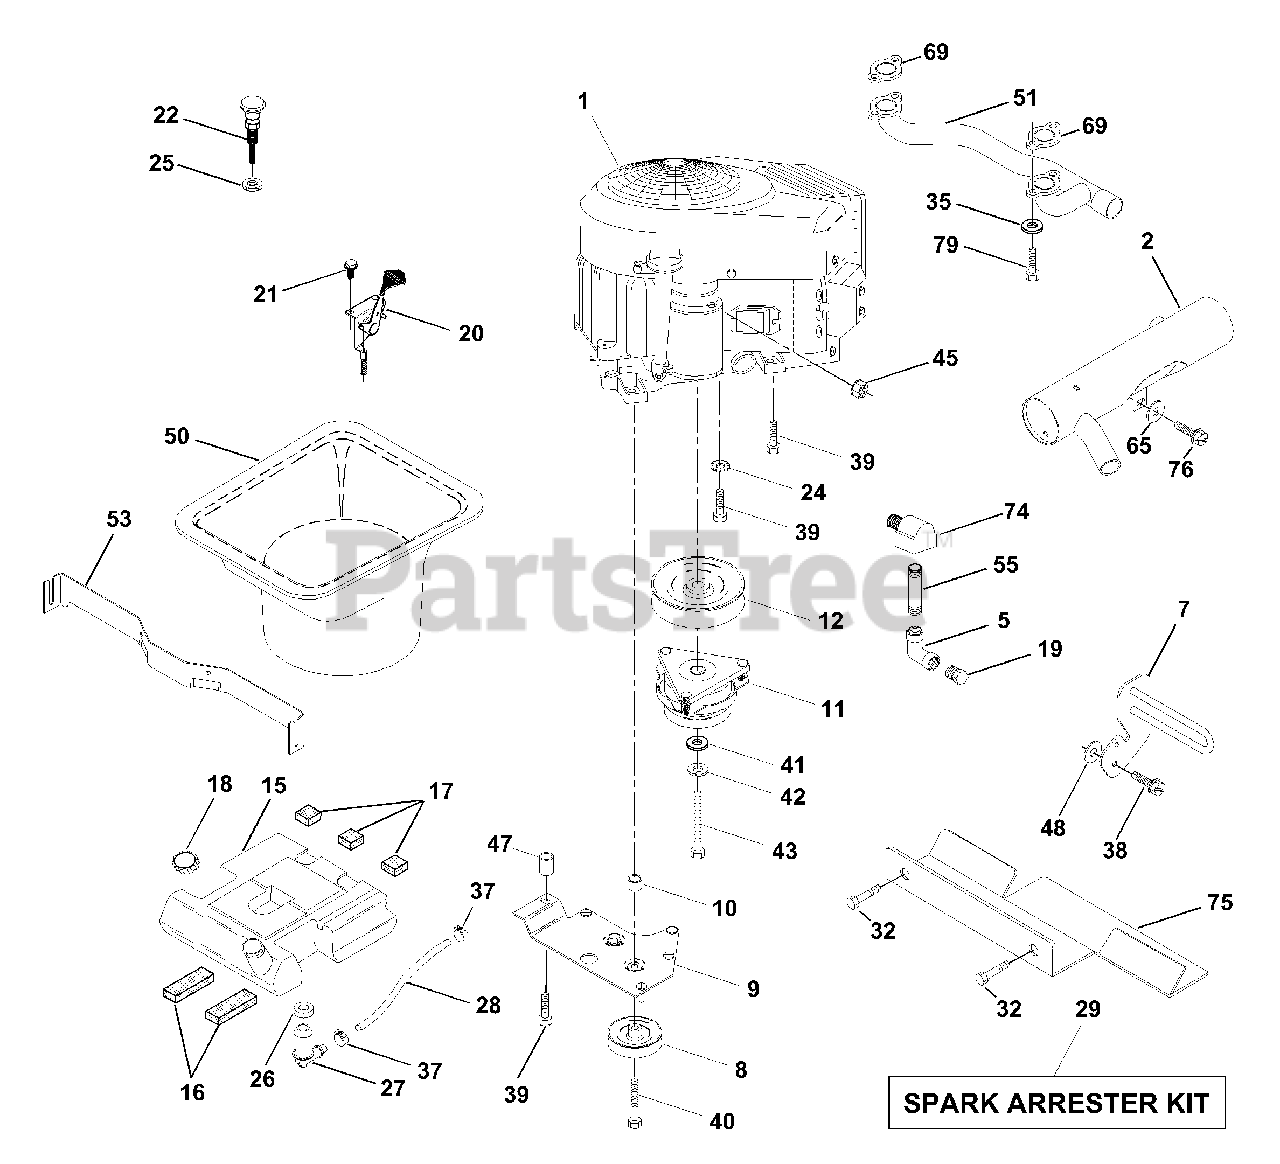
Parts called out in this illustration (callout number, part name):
2	Muffler Side
5	Elbow STD 90 Degree 3/8 - 18 NPT
7	Muffler Assembly Guard
8	Pulley V-Idler
9	Keeper Asm. Belt Engine VGT96
10	Bushing
11	Clutch Electric
12	Pulley Engine VGT Elect Clutch
15	Tank Fuel Rear 3.50 YT/GT 96
16	Pad Spacer
17	Pad Spacer
18	Cap Asm Fuel W/Sym Vented
19	Plug Oil Drain
20	Control Throttle
21	Screw Hex Thd Cut 1/4 - 20 X 5/8
22	Control Choke
24	Washer Ext Tooth 3/8
25	Nut, Keps 3/8-24 UNF
26	Bushing
27	Stem Tank Fuel
29	Spark Arrester Kit
32	Screw Thdrl 5/16-18 x 1/2
35	Washer Lock Hvy HLCL Spr 5/16
37	Clamp Hose
38	Screw 3/8-16 x 1-1/4
39	Screw TT 3/8-16 x 2-1/4 UNC
40	Screw TT 3/8-16 x 4 UNC
41	Washer 1-1/2 OD X 15/32 ID X .250
42	Washer Lock 7/16
43	Bolt, Hex 7/16-20 x 4-1/4 5 Ga. 1.38
45	Nut Keps Hex 1/4-20 UNC
47	Spacer Engine CV22 Round PM
48	Washer 13/32 x 1-1/4 x 7 Ga.
50	Duct Air Intake
51	Manifold VGT
53	Rod Support Hood Duct
55	Nipple, Pipe 3/8 NPT x 4-1/2
65	Washer 13\32 x 1 x 14 Ga.
69	Gasket
74	Elbow Street Brass
75	Shield Heat Intek VGT
76	Screw Hexwsh Thdrl 3/8-16 x 3/4
79	Screw Hex Hd Cap 5/16-18 x 3/4
